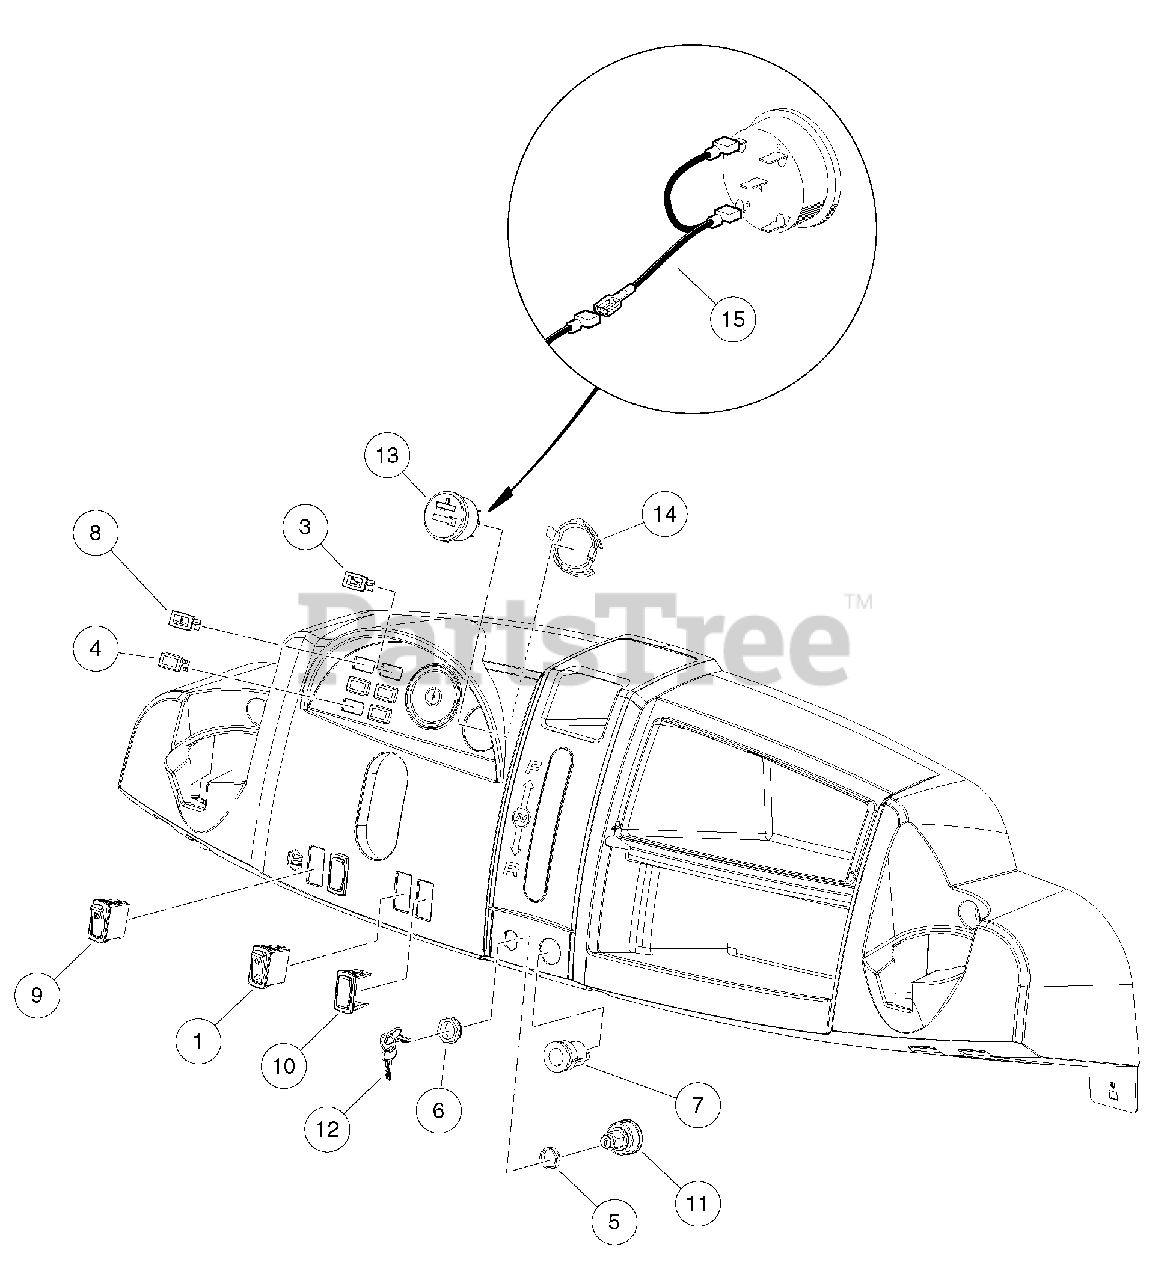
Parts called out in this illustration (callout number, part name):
1	Switch, Rocker, Spring Return, Bed Lift
2	Instl, Elec, Restyle Diesel Se
3	Light, Oil
4	Plug, Hole
5	Spacer, Keyswitch
6	Nut, Key Switch
7	Receptacle, Accessory
8	Light, Indicator, Coolant Temp
9	Switch, Rocker, Light
10	Cover, Hole, Switch, Rocker
11	Keyswitch, 12v, Diesel
12	Keys (set of 2)
13	Gauge Fuel-hour Sep Gnd
14	Clip, Meter, Round
15	Asm Wire Meter F-h Jumper
